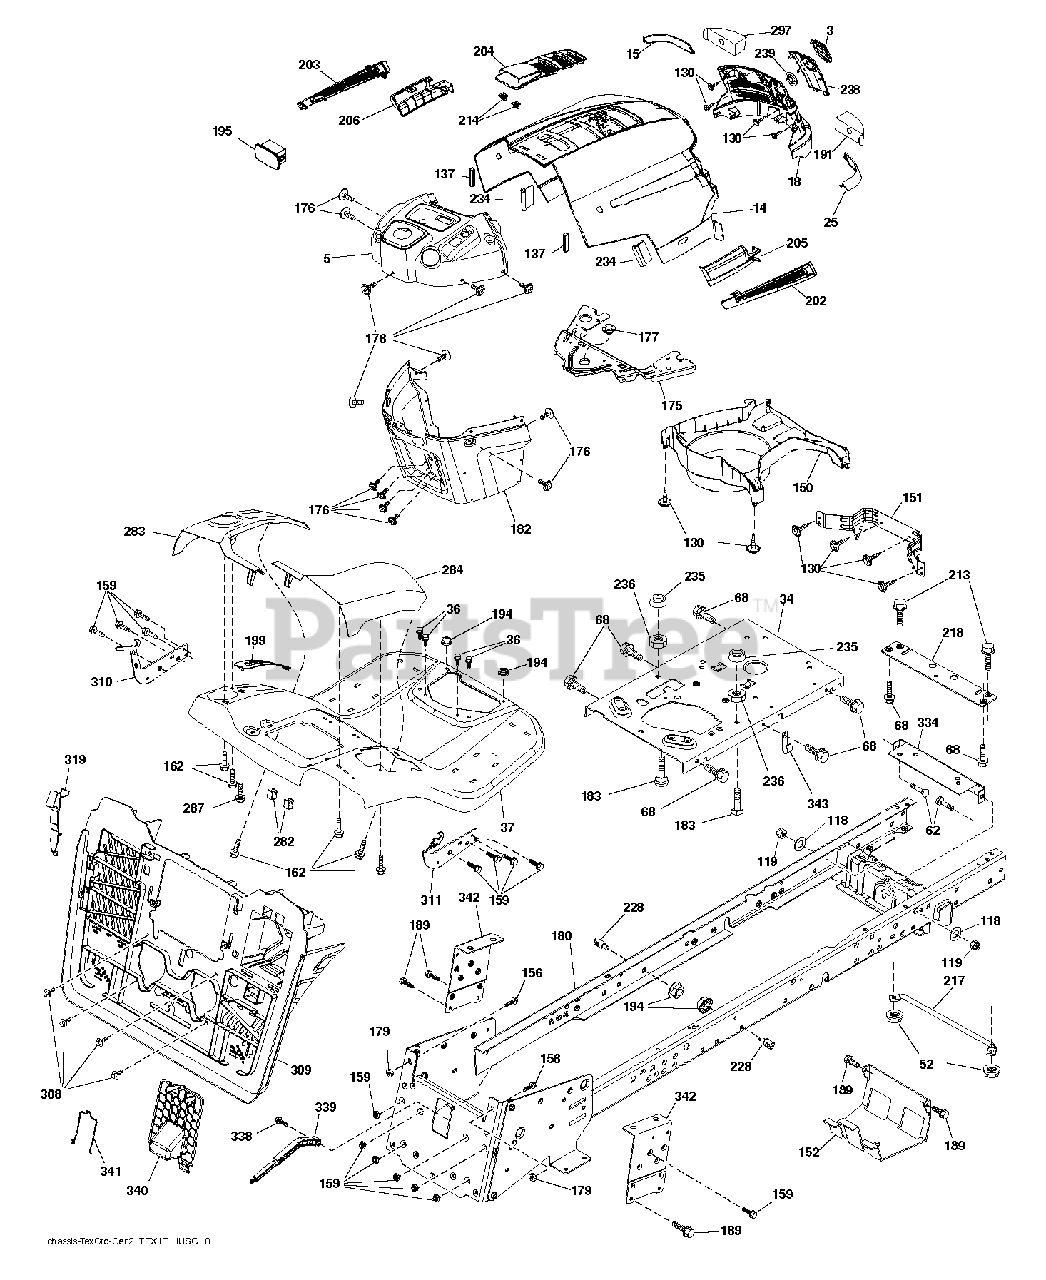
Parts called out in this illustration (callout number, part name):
3	LOGO.HUSQ.GT.LT.CROWN.H
5	SUBASM.DASH.UPPER.HLT.498
14	HOOD.HUSQVARNA.LT.ORANGE
15	LENS.HUSQVARNA LT.RH
18	GRILLE.SVC.HUSQVARNA.GREY
25	LENS.HUSQVARNA LT.RH
36	SCREW 5/16"
37	FENDER.TEX.SRD.CRD.FRN.GUARDS
52	LOCKNUT
62	BOLT D
68	SCREW LT
118	WASHER
130	SCREW.#10 X 0.750.BOS
137	BUMPER DASH
151	BRACKET PIVOT
152	SHIELD.BROWNING.W/TEX
159	SCREW, 3/8-16X3/4
162	SCREW.HI-LO.CONSOLE
175	CROSSMEMBER
176	SCREW.#10-24X5/8.RN.QU
177	BUSHING STEERING
182	DASH.LOWER.PREDATOR LT
183	BOLT.5/16-18X1-1/4 FULL THD
189	SCREW
191	INSERT.REFLECTIVE.RH.
194	NUT LOCK HEX FLANGE 5/16-18
195	PLUG.HOLE.DASH.LOWER.12V.BLK
199	PLATE DECK LIFT
202	VENT.SIDE.HUSQVARNA.LT.RT
203	VENT.SIDE.HUSQVARNA.LT.LFT
204	SUBASM.TOP.VENT.HUSQ.LT
205	SKIRT.SIDE.HUSQVARNA.LT.RT
206	SKIRT.SIDE.HUSQVARNA.LT.LEFT
213	BOLT
214	CLIP.RETAINER.TINNER.
217	ROD.PIVOT.HOOD
218	X-PIECE.HOOD.STOP.NON/
228	STUD.FASTNER.W/ANTI-ROTATE
234	BUMPER.HOOD.TEX.HUSQVARNA
235	SPACER FENDER
236	NUT.CENTERLOCK.5/16-
238	TRIM.HUSQ LT.668
282	CLIP.RETAINER.CONSOLE.LT.HUSQ
283	CONSL.DECKLIFT.LH.SRD.TEX.CRD
284	CONSL.SHFT.PEDAL.RH.SRD.TEXCRD
287	SCREW 1/4X20
297	INSERT REFLECTIVE
308	BOLT, 5/16-18 X 1 3/4
310	LH.ADJUST.HANGER.BRACKET.ASM
311	RH.ADJUST.HANGER.BRACKET.ASM
319	BRACKET.ACTUATOR.BAGGER.SRD
334	BRACKET.ENGINE
338	BOLT BOLT SHOULDER
339	LEVER LEVER BAGGER
340	DOOR.PNT.BATTERY.TRY.TEX.CRD.
341	LATCH
342	SUPPORT SUPPORT FENDER
343	CLIP CLIP
